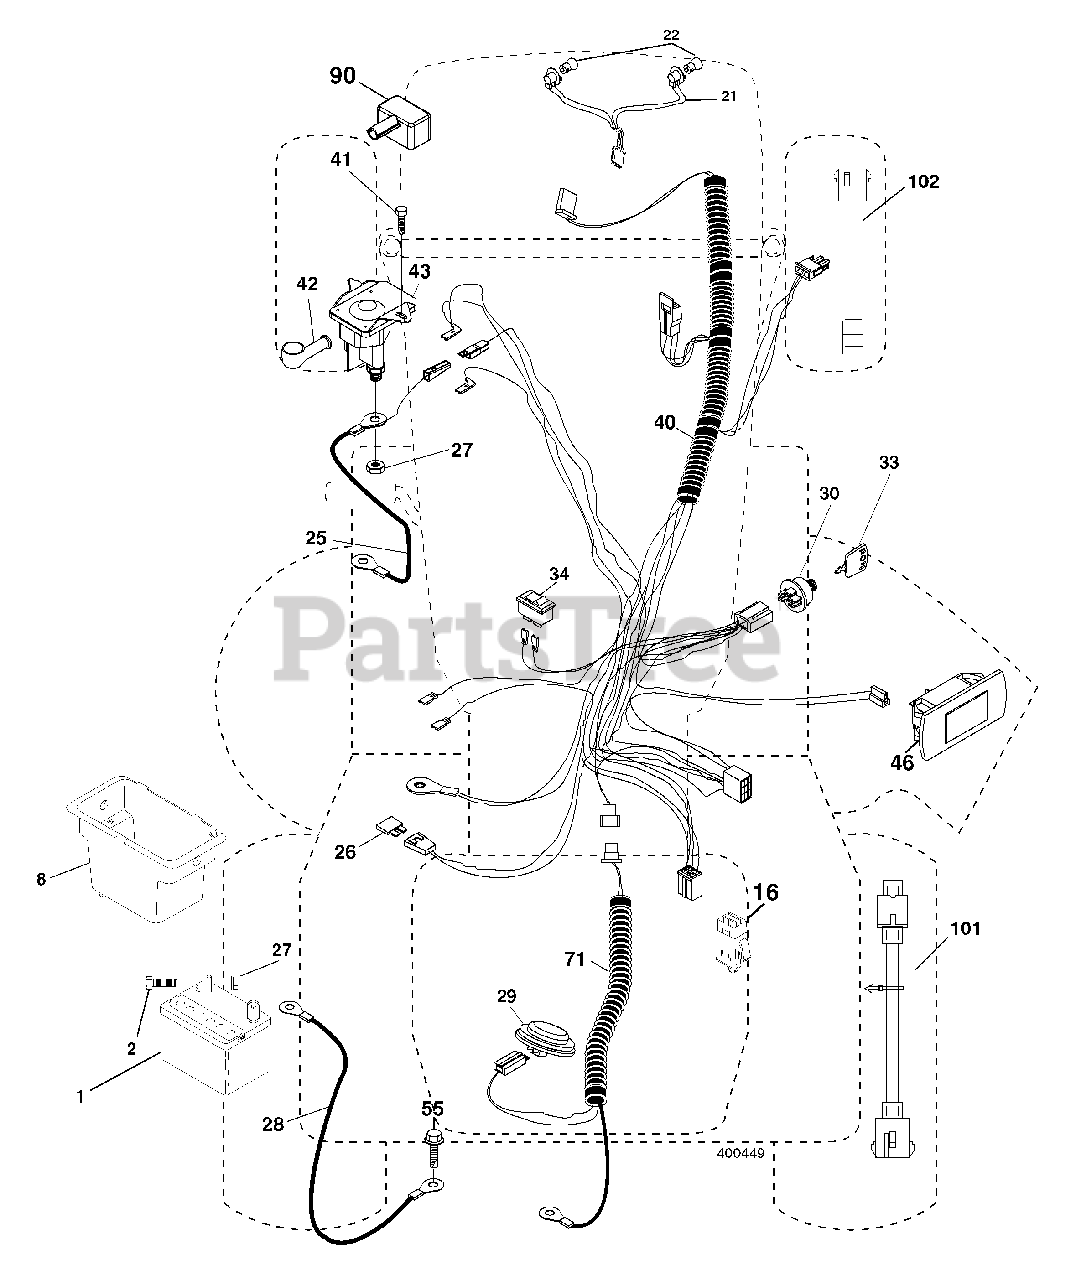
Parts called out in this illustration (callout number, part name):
1	Battery
2	Bolt Hex Hd 1/4-20 unc x 3/4
8	Battery Box
16	Switch Interlock
21	Harness Socket Light
22	Bulb, Light # 1156
25	Cable Starter
27	Nut Keps Hex 1/4-20 unc
28	Cable Ground
29	Switch Seat
30	Switch Ign
33	Key Ign Molded Generic
34	Switch Light/Reset
40	Harness Ign. Dash
41	Screw Thd Cut 1/4-20 x 1/2
42	Cover Terminal Red
43	Solenoid
46	Gauge Hourmeter
50	Switch PTO
55	Screw Thdrol 5/16-18 x 3/4
71	Harness Chassis
90	Cover Terminal Battery
101	Pigtail Harness Clutch
102	Harness Pigtail
